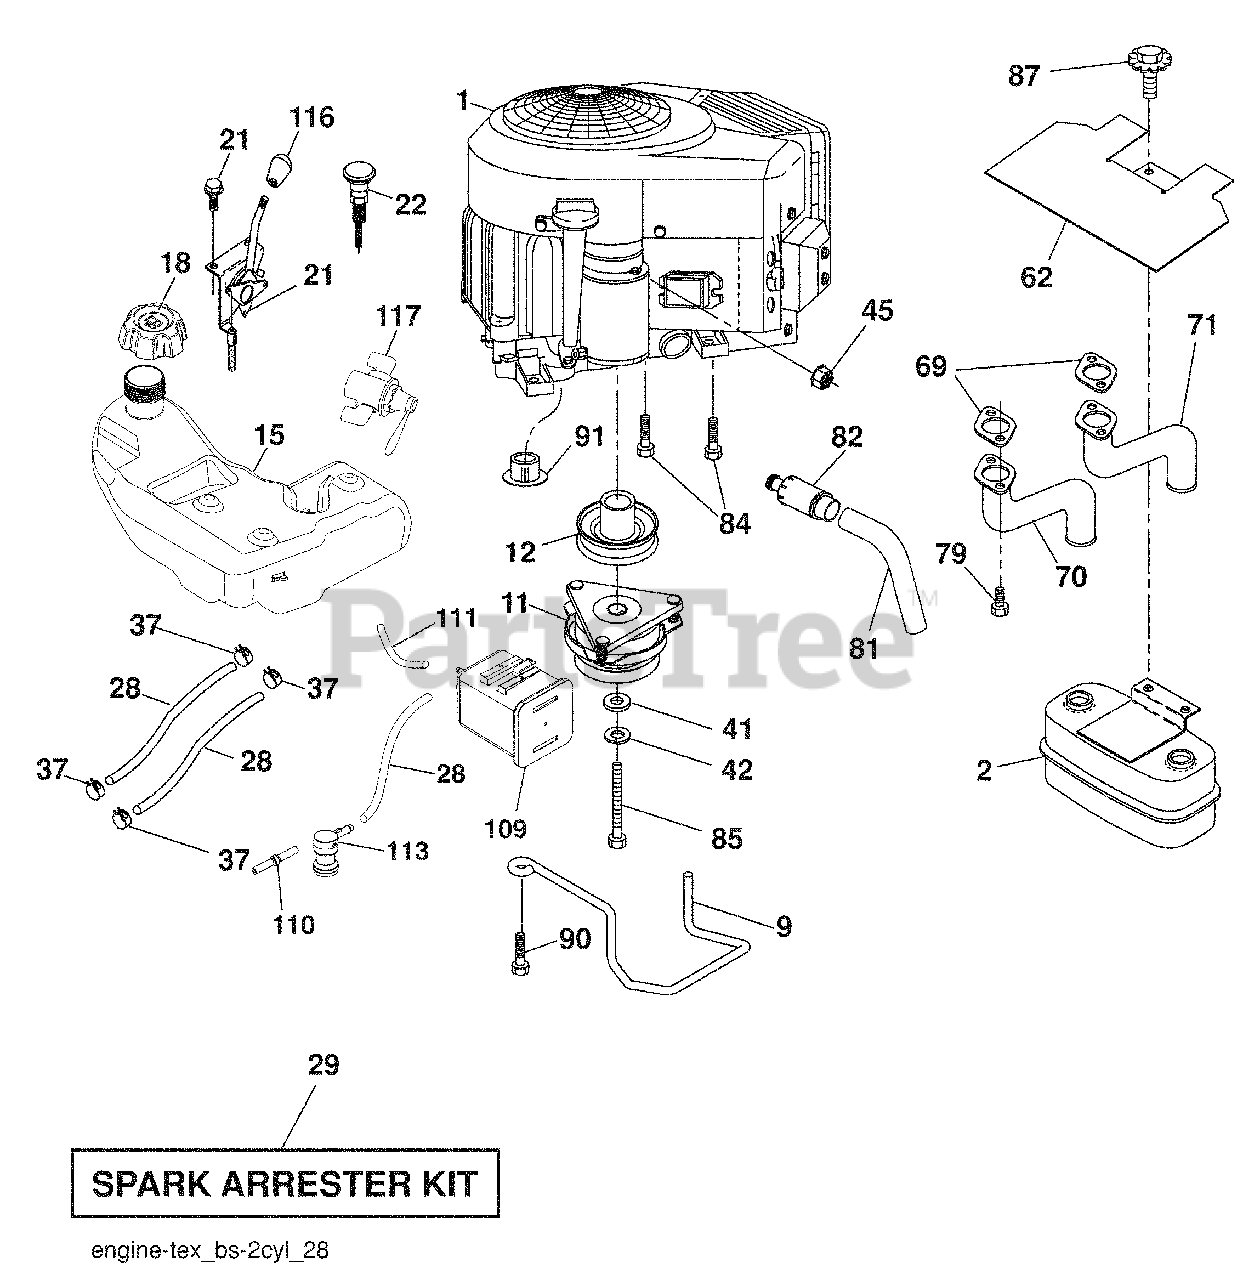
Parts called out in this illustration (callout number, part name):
9	Keeper Belt Engine
11	Clutch
12	Pulley Engine
15	Tank Fuel
18	Cap Asm
20	Control Throttle
21	Screw #10 x .750 BOS Thread
28	Fuel Line
29	Spark Arrester Kit
37	Clamp Hose
41	Washer 1-1/2 OD x 15/32 ID x .250
42	Washer Lock 7/16
45	Nut Keps Hex 1/4-20 unc
62	Heat Shield
70	Exhaust Tube LH
71	Exhaust Tube RH
79	Screw Tube Muffler
81	Tube Drain Oil Easy
82	Plug Drain Oil
84	Screw 3/8-16 x 1-1/4
85	Bolt Hex 7/16-20 x 4 x Gr. 5-1.5 Thr
87	Bolt 5/16-18 unc x 3/4 w/Sems
90	Screw 3/8-16 x 1
109	Canister Carbon Filter asm
110	Valve Anti Slosh
111	Purge Line
113	Valve Slant Cartrdg
116	Knob Soft Touch
117	Fuel Valve
